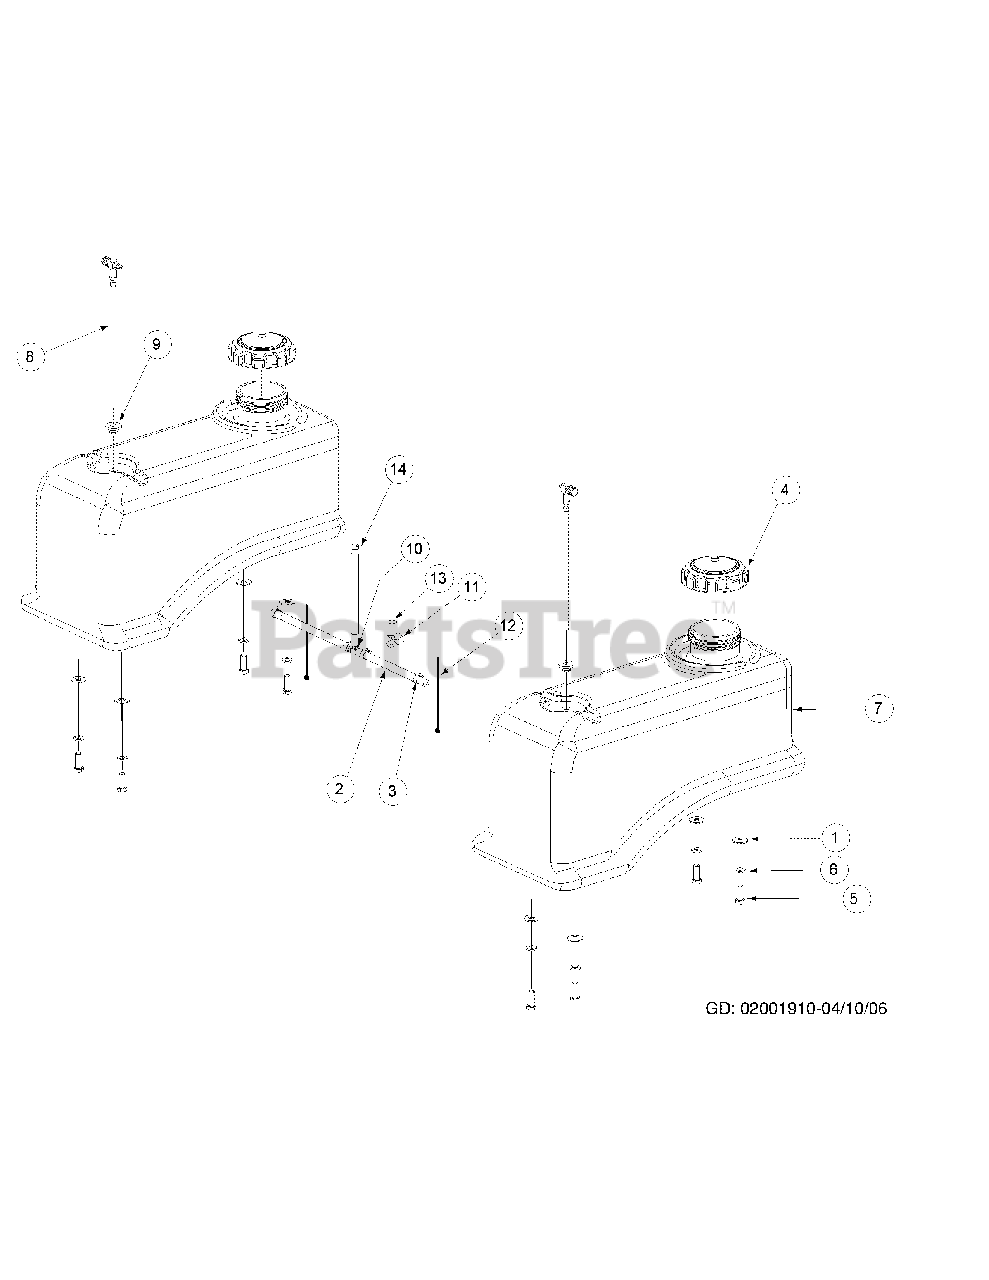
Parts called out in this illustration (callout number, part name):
1	Flat Washer, .406 ID, 1.0 OD, .105
2	Hose, 1/4" Fuel Line (79.5 in inches)
3	Clamp, Union
4	Fuel Cap, 3.5
5	Hex, Cap Screw, 3/8-16, .88
6	Lock Washer, 3/8
7	Fuel Tank
8	Fuel Fitting
9	Grommet, Fuel Tank
10	Tee Fitting, Fuel
11	Clamp, 1/2 Tubing
12	Cable Tie
13	Flat Washer, 1.4 x .630 x .0515
14	Hose Clamp, SAE #4: 1/4-5/8, SS
